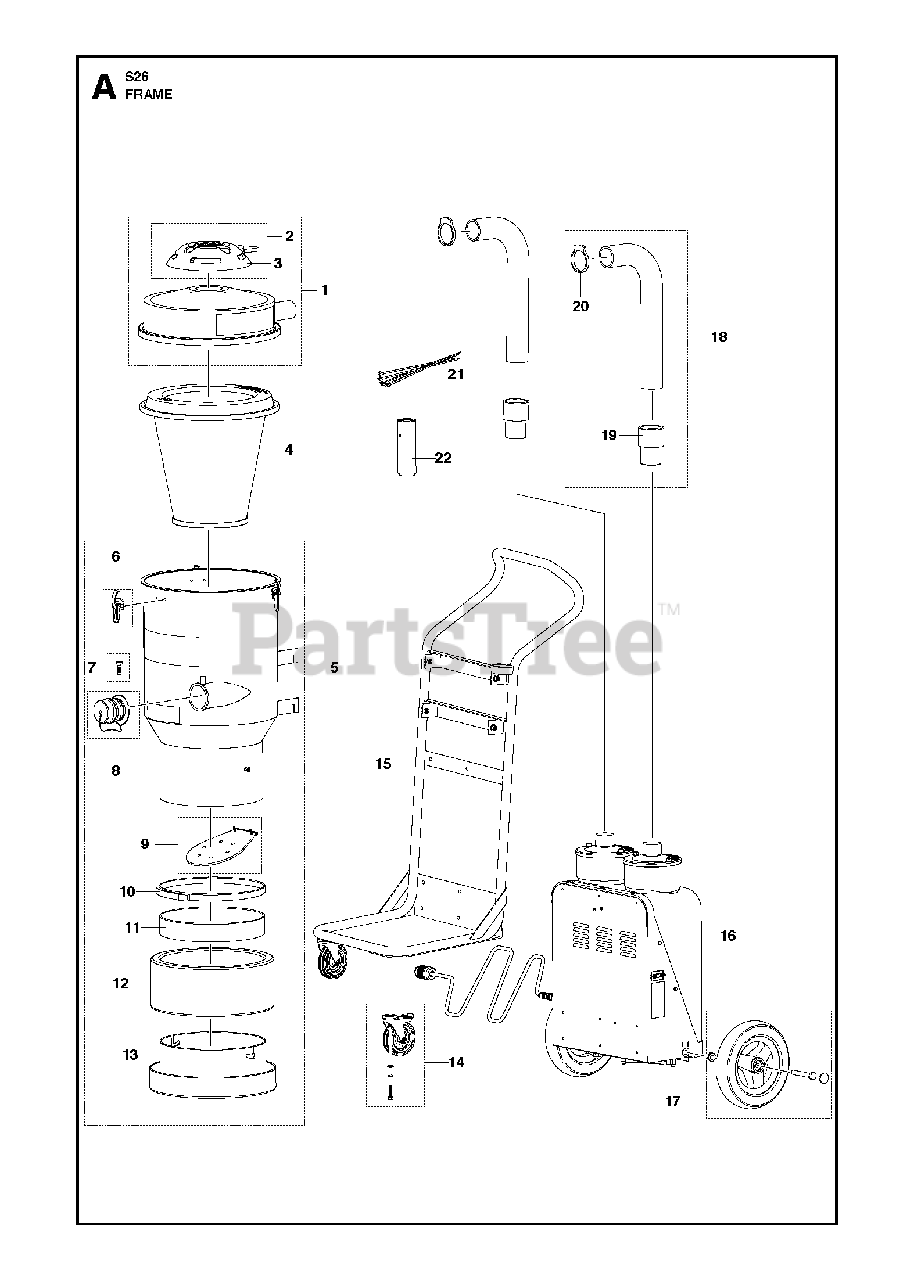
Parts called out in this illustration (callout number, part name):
16	MOTOR HOUSINGMOTOR HOUSING, WITH MOTOR 230V, S26
16	MOTOR HOUSINGMOTOR HOUSING, WITH MOTOR 120V, S26
16	MOTOR HOUSINGMOTOR HOUSING, WITH MOTOR 230V (US), S26
